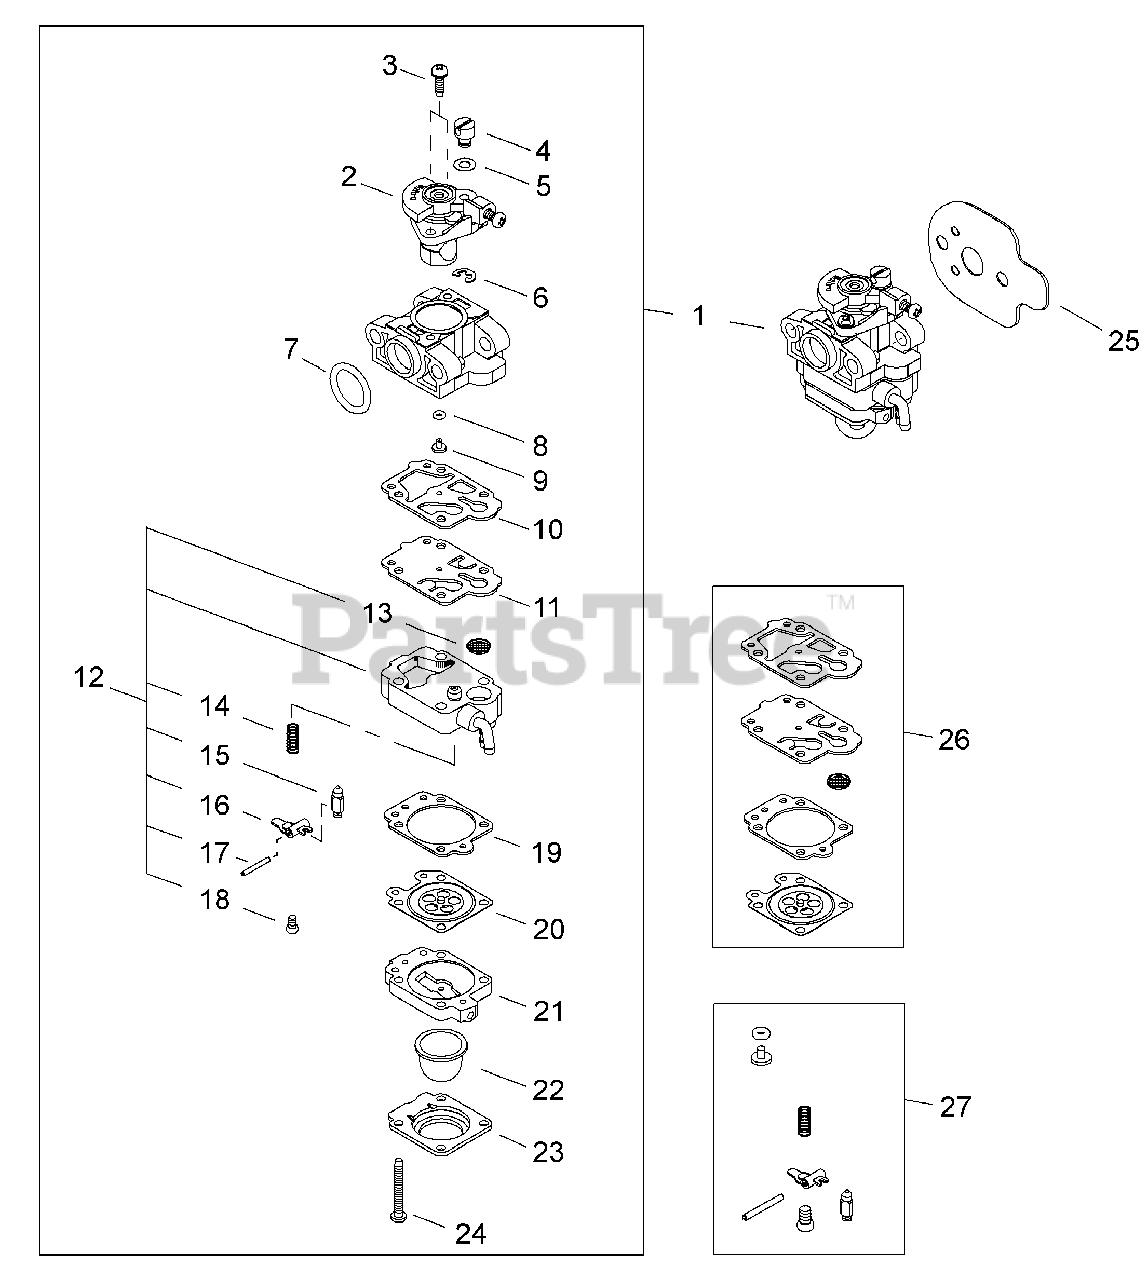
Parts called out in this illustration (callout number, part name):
1	CARBURETOR
2	VALVE ASSY, THROTTLE
3	SCREW, THROTTLE COLLAR
4	SWIVEL
5	WASHER
6	E-RING
7	O-RING 15
8	O-RING
9	JET, MAIN
10	GASKET, PUMP
11	DIAPHRAGM, PUMP
12	BODY ASSY, PUMP
13	SCREEN, FUEL INLET
14	SPRING, METERING LEVER
15	VALVE, INLET NEEDLE
16	LEVER, METERING
17	PIN, METERING LEVER
18	SCREW
19	GASKET, METERING DIAPHRAGM
20	DIAPHRAGM, METERING
21	BODY ASSY, PURGE
22	BULB, PURGE
23	RETAINER, PURGE BULB
24	SCREW
25	GASKET, INTAKE
26	GASKET / DIAPHRAGM KIT
27	VALVE KIT, INLET NEEDLE
